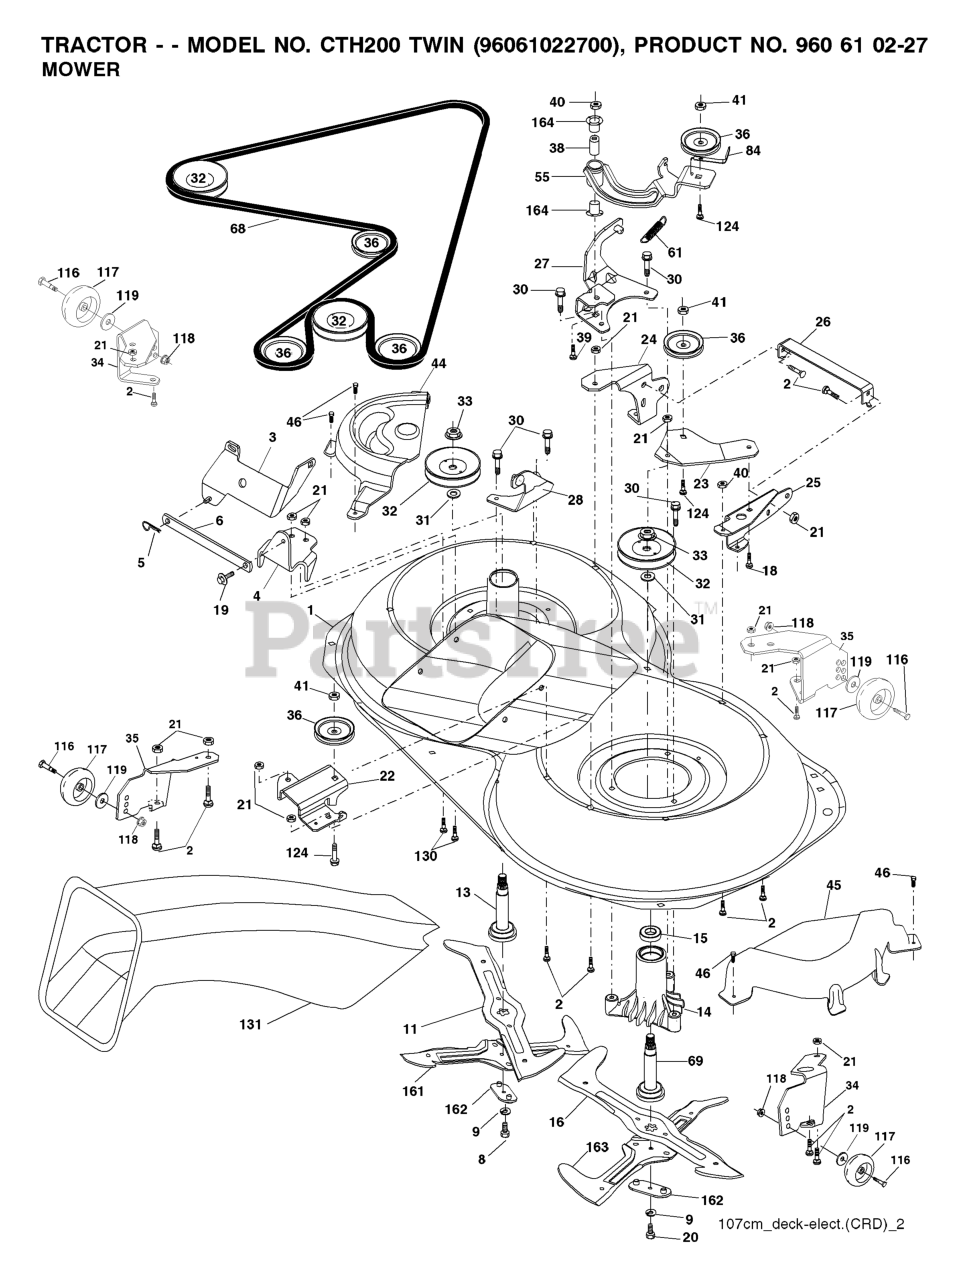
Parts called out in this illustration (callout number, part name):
1	DECAL.WARN.START.INSTRUCTIONS
2	DECAL,ETHANOL E85 WARNING
4	DECAL.FENDER
5	DECAL.MOWER
8	DECAL.MOWER.SCH.48/54
9	DECAL BTRY SYMBOLS
14	DECAL.PNL.SD.LGT2554.KOHL.
15	DECAL HOOD CUST. RESP.
16	DECAL.HOOD.LOGO.ORANGE.HUSQVAR
17	DECAL.RPL.SV730,
